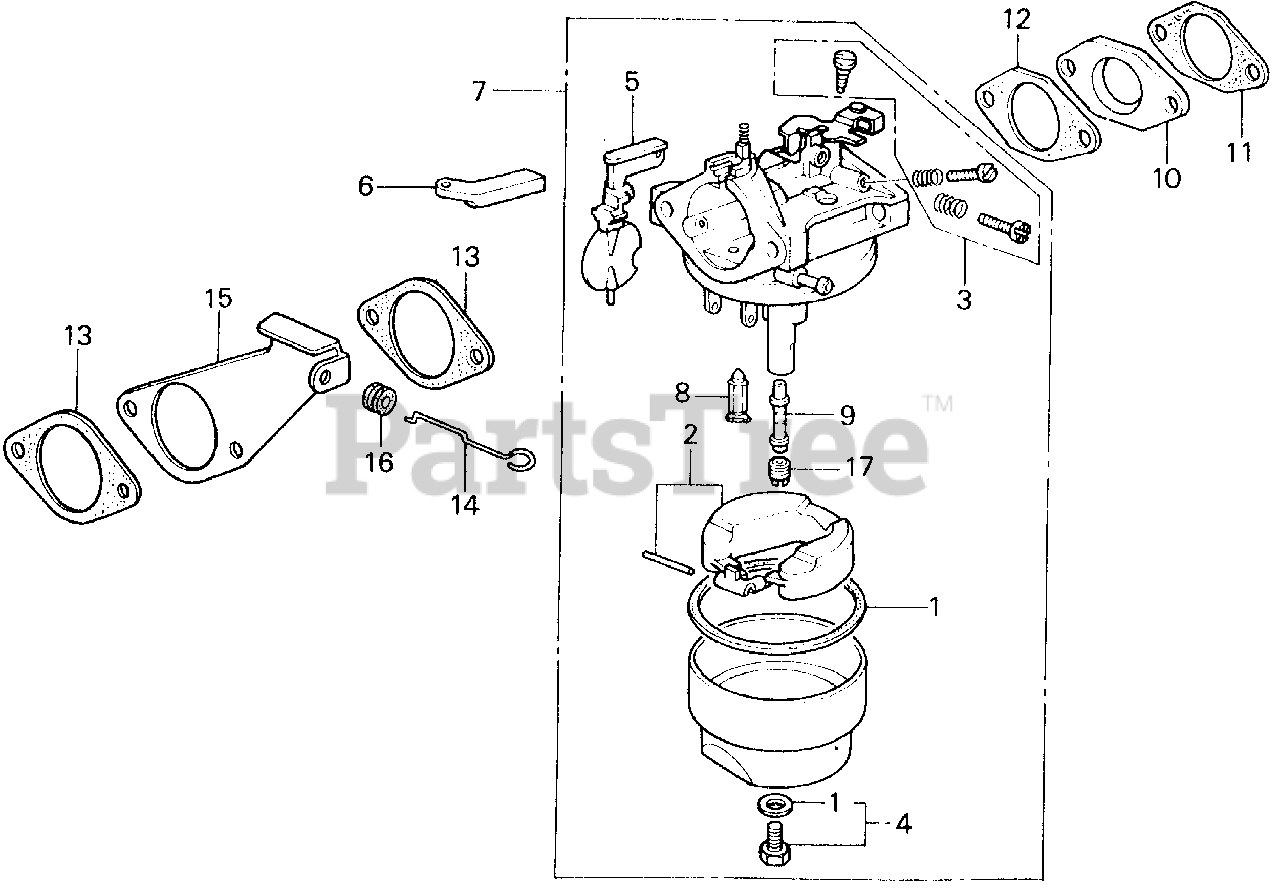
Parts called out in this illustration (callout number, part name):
1	GASKET SET
2	FLOAT SET
3	SCREW SET A
4	SCREW SET B
5	CHOKE SET
6	ARM, CHOKE LEVER
7	CARBURETOR ASSY.
7	CARBURETOR ASSY. (BB28B A/B)
8	VALVE, FLOAT
9	NOZZLE, MAIN
10	INSULATOR, CARBURETOR
11	GASKET, INSULATOR
12	GASKET, CARBURETOR
13	GASKET, AIR CLEANER
14	ROD, CHOKE CONTROL
15	STAY, CHOKE CONTROL
16	GROMMET, CHOKE ROD
17	JET, MAIN (#62)
17	JET, MAIN (#65)
